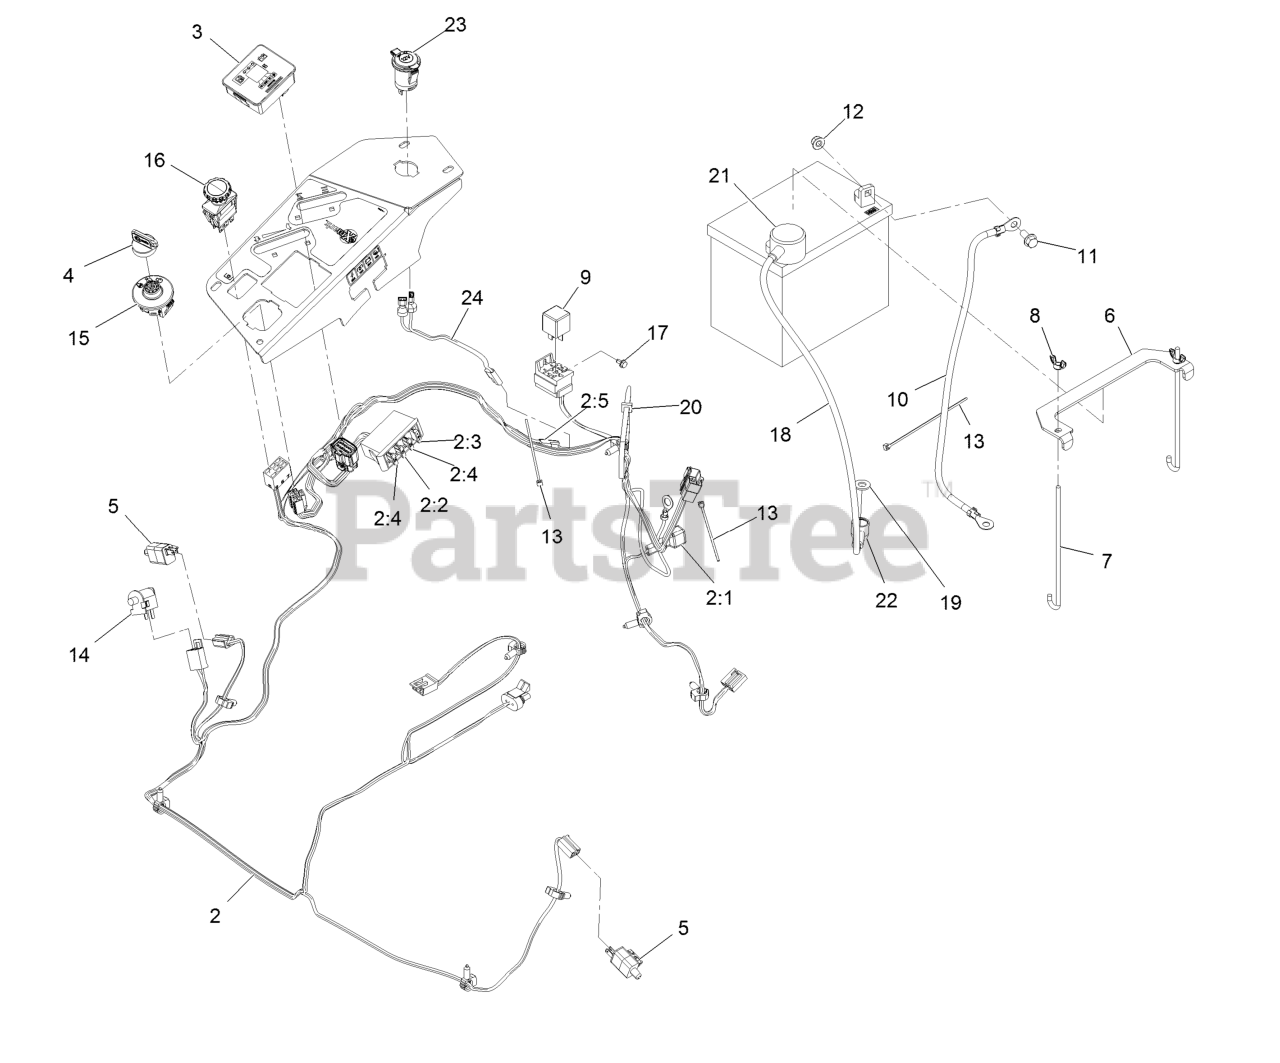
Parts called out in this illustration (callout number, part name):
2	Harness-Wire, Main
2:2	Fuse-Blade, 10 Amp
2:3	Fuse-Blade, 15 Amp
2:4	Fuse-Blade, 25 Amp
2:5	Cap-Plug
3	Fuel/Hour Meter ASM
4	Key-Ignition
4	Key-Exmark Logo
6	Strap-Tie Down, Battery
7	Bolt-Holddown
8	Wingnut-Nyloc 1/4-20
9	Relay-12Vdc 40 Amp
10	Cable-Battery, Negative
11	Screw-HH Flg 5/16-18 X 3/4
12	Nut-Nyloc 5/16-18 Flg
13	Tie-Cable 5 1/2 (Small)
15	Switch-Ignition
16	Switch-PTO, 10 Amp
17	Screw-HWH #10-24 X 3/8
18	Cable-Battery, Positive
19	Washer-3/8 SAE
20	Tie-Cable 7 15/16 (Large)
21	Insulator-Battery
22	Insulator-Solenoid
23	Port-Power, 12V
24	Harness, Receptacle 12V
